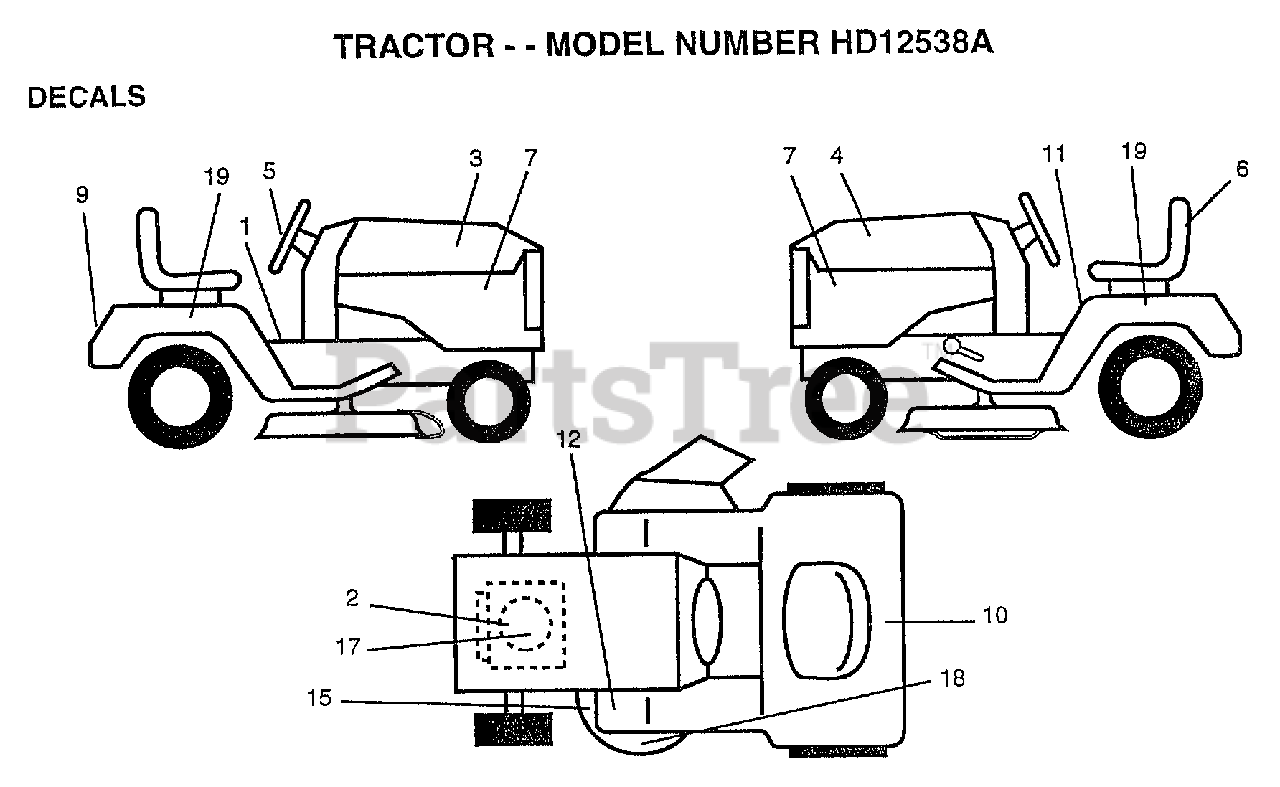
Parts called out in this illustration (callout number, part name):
2	DECAL, HP ENGINE
3	"DECAL HOOD,RH"
4	DECAL HOOD LH
5	"DECAL INS,STRG WH"
6	"DECAL SEAT,REPLCM"
7	"DECAL PENL,SIDE"
9	DECAL-FENDER
10	DECAL.BATRY.3-3908
11	"DECAL FENDER,DANG"
12	DECAL CLUT/BRAKE
15	DECAL
17	"DECAL ENGINE,REPL"
18	"DECAL MOWER,HOME"
19	"DECAL FENDER,5 SP"
